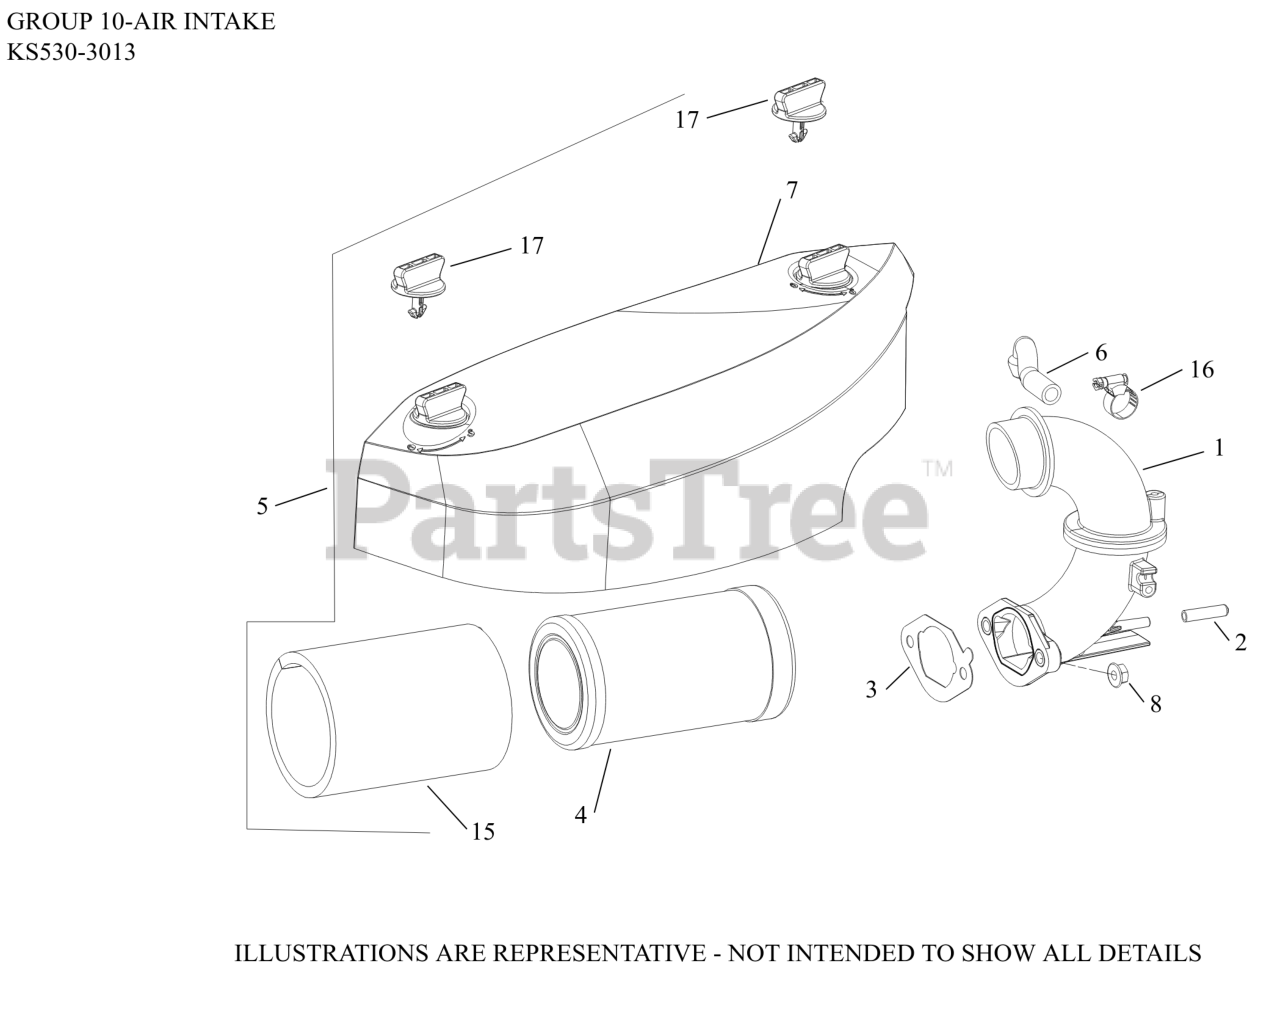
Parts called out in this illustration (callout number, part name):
1	ADAPTER, AIR CLEANER ASSY
2	CAP, MASKING
3	GASKET, CARBURETOR
4	ELEMENT, AIR FILTER
5	AIR FILTER KIT (STD)
6	HOSE, BREATHER
7	COVER, AIR CLEANER ASSY
8	NUT, FLG M6X1.0
15	ELEMENT, PRE-CLEANER
16	CLAMP, HOSE (KM)-USE 25 237 31-S
17	KNOB, AIR CLEANER COVER
